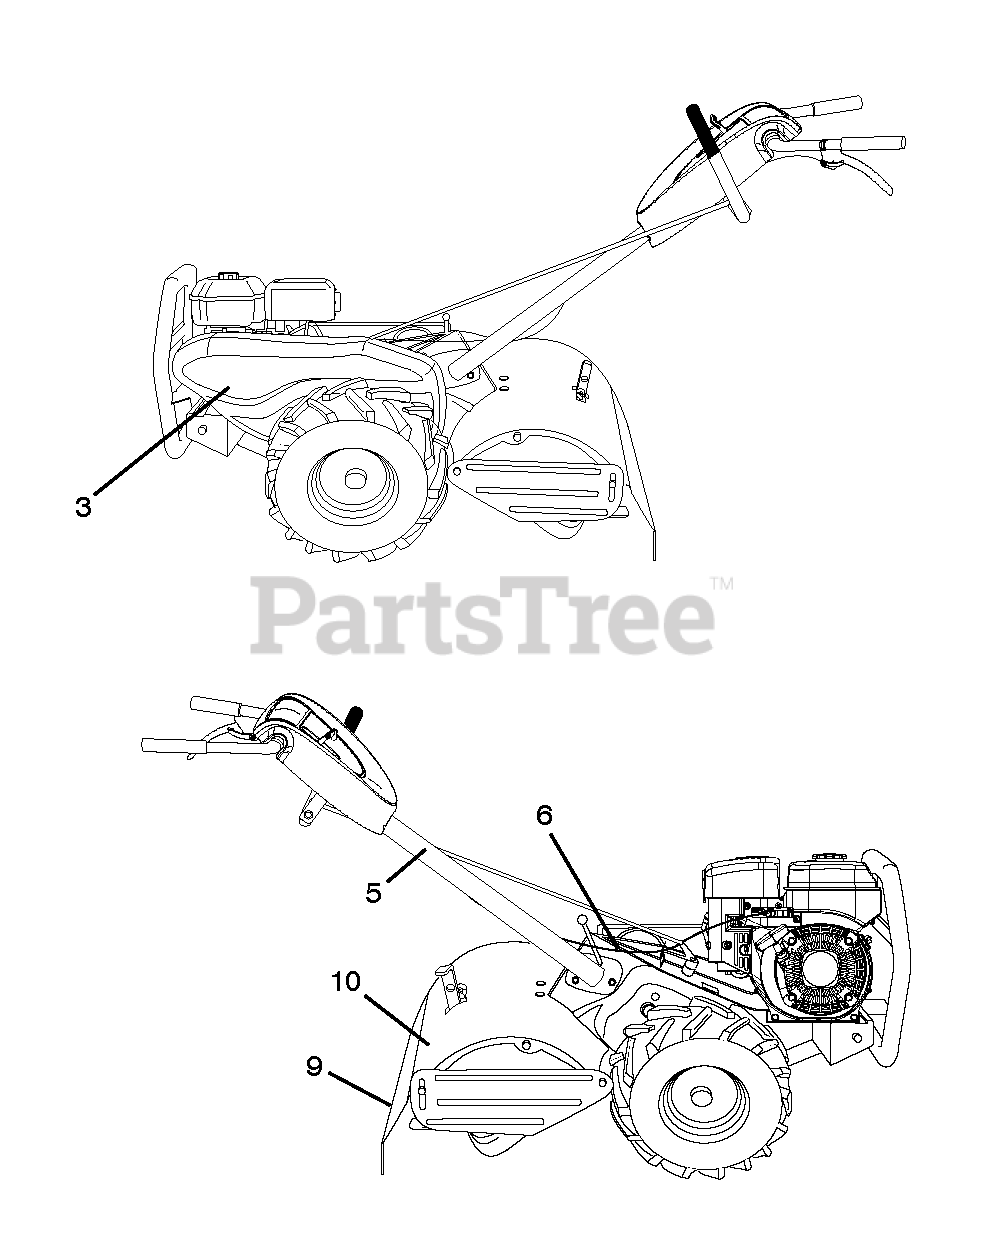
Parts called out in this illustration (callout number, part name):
3	RP.DECAL.BADGE.170MM.TEXTLOGO
5	DECAL.PLACEMENT.HAND.SYMBOLS
6	DECAL.SHIFT.INDICATOR.TILLER
9	DECAL.WARNING.4-SYM.TILLER.INT
10	DECAL EUROPE STANDARD CE
